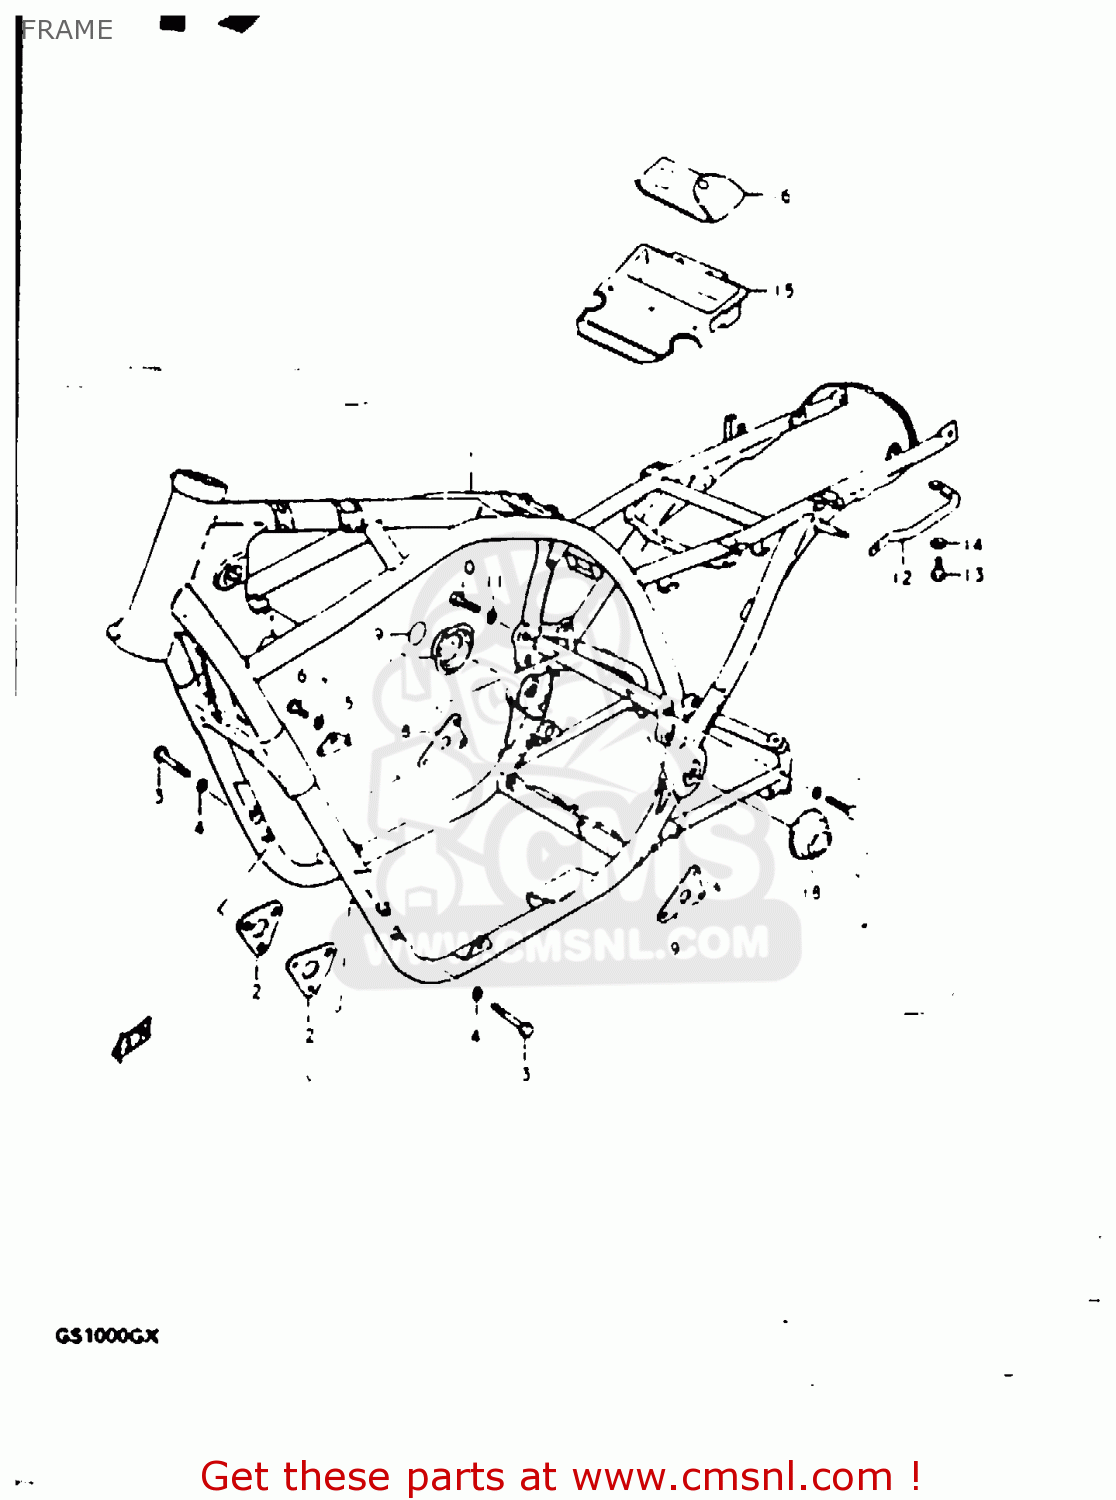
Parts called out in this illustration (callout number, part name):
1	FRAME
2	PLATE,ENGINE MOUNTING
3	BOLT
4	LOCK WASHER
5	PLATE, NO.2 (BLACK)
6	BOLT
7	LOCK WASHER
8	PLATE,ENGINE MOUNTING
9	PLATE,ENGINE MOUNTING
10	BOLT 8X40
11	LOCK WASHER
12	GRIP,FRAME
13	BOLT
14	WASHER
15	HOLDER,TOOL
16	TOOL SET
17	COVER,REAR SWING ARM PIVOT
18	COVER,SWINGINGARM PIVOT,L
19	TAPE,REAR SWING ARM PIVOT
